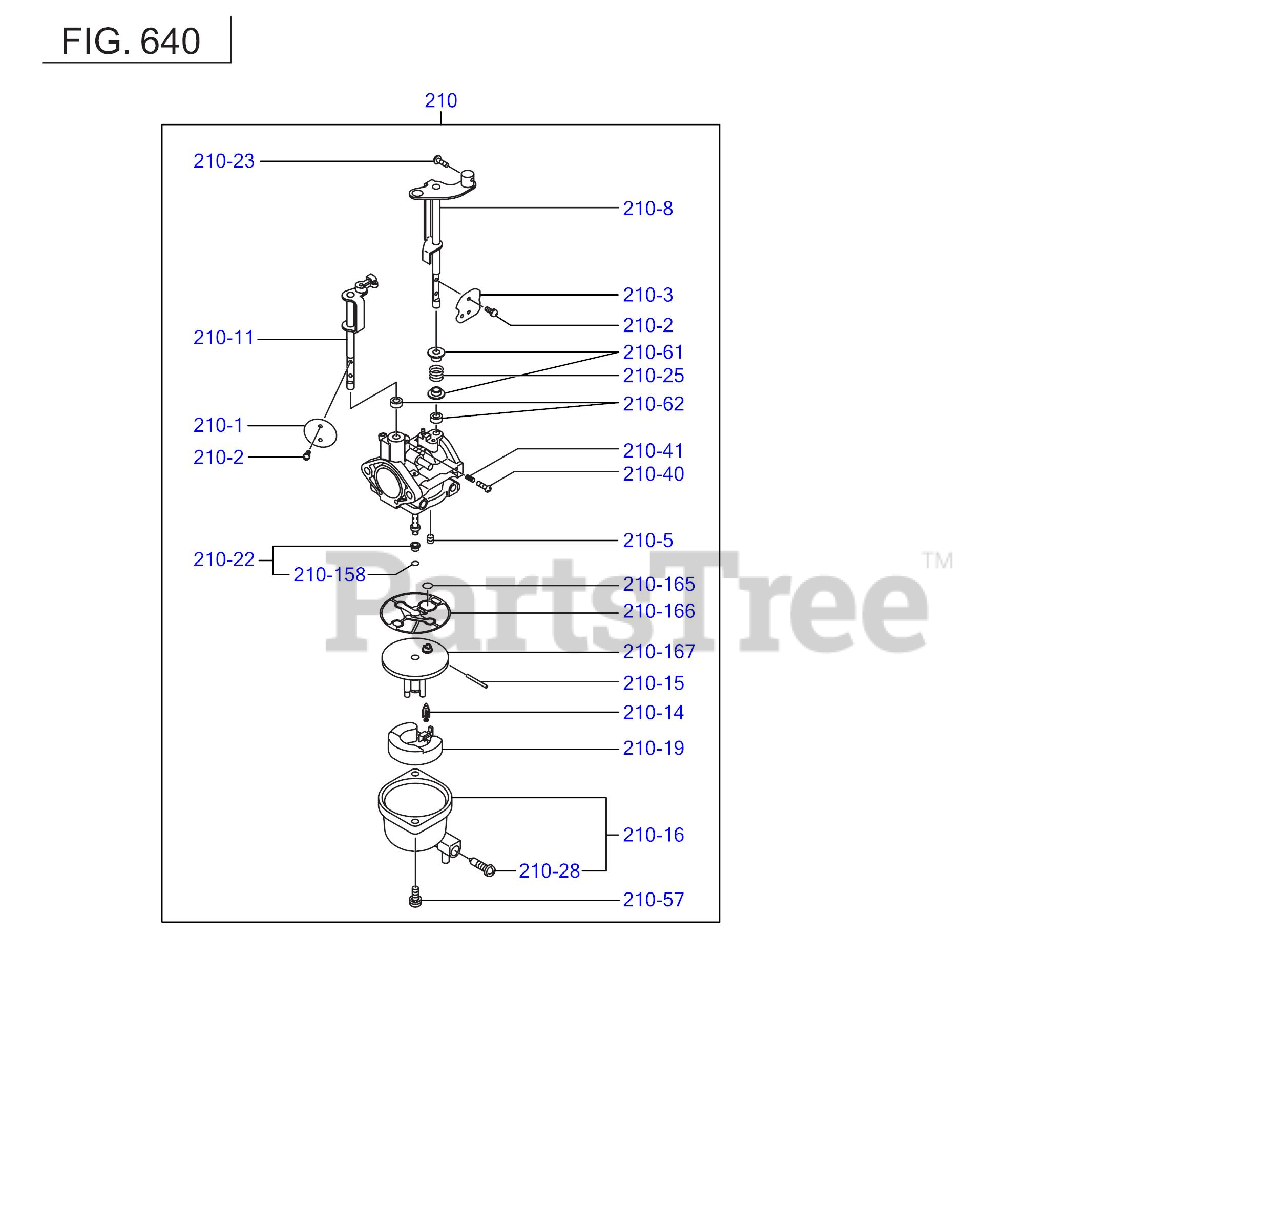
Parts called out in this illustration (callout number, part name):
210-1	VALVE,THROTTLE
210-2	SCREW,VALVE SET
210-3	VALVE,CHOKE
210-5	JET,SLOW (#40)
210-8	SHAFT,CHOKE
210-11	SHAFT CP THROTTLE
210-14	VALVE AY FLOAT
210-16	CHAMBER CP,FLOAT
210-22	JET,MAIN (#117)
210-23	SCREW
210-25	SPRING,CHOKE RETURN
210-28	SCREW,DRAIN
210-40	SCREW,THRO.ADJUST
210-41	SPRING,THR0.ADJUST
210-61	COLLAR,CHOKE
210-62	SEAL LIP
